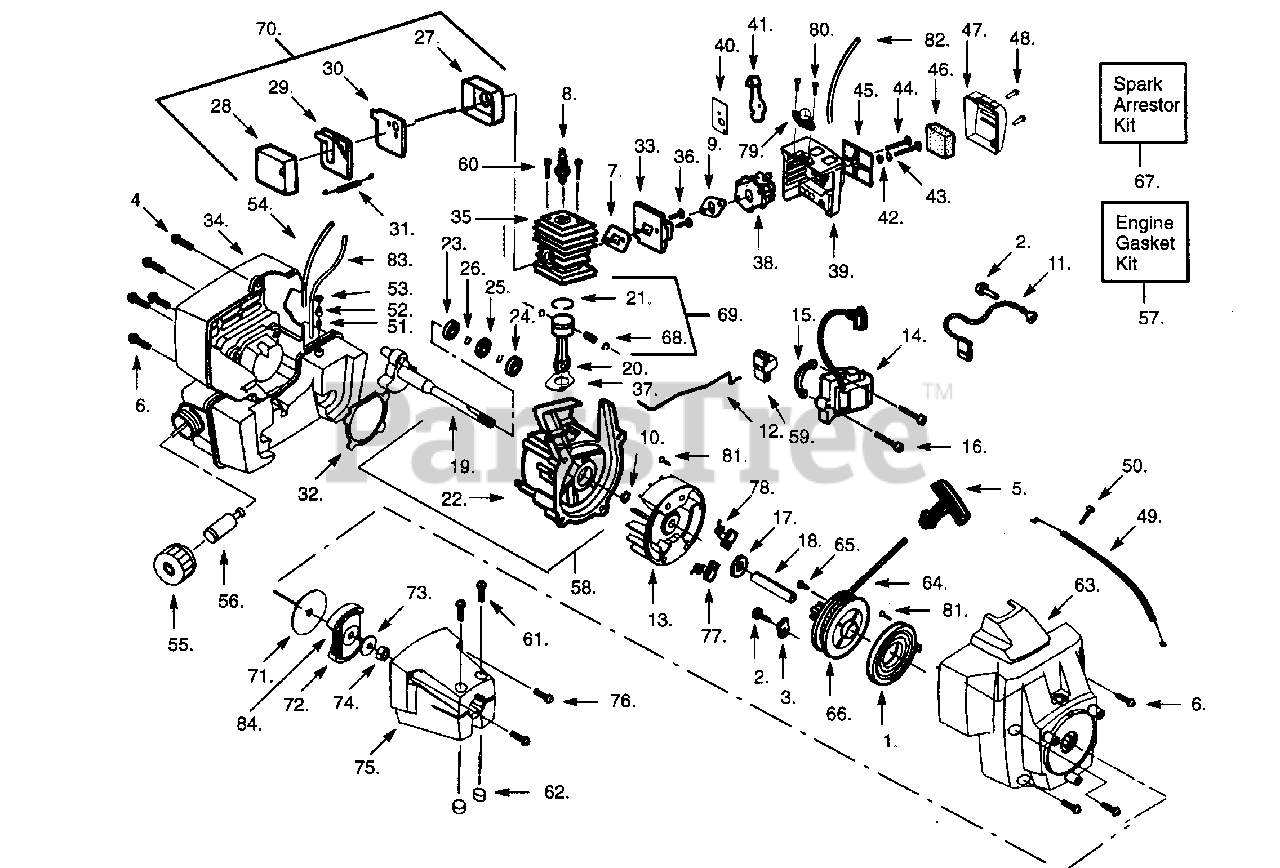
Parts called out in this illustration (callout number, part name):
1	Starter Spring
3	Retainer
5	Starter Handle
6	Screw
7	Cylinder Gasket
8	Spark Plug
10	Retainer
11	Lead Wire
12	Switch Wire Form
13	Flywheel Ass'y.
14	Ignition Module
19	Crankshaft Ass'y.
20	Connecting Rod Ass'y.
21	Piston Ring
22	Crankcase Ass'y.
23	Inner Bearing
24	Outer Bearing
25	C'case Seal
26	Retaining Ring
27	Muffler Body
28	Muffler Cover
29	Muffler Baffle-Exit
30	Muffler Baffle-First
31	Muffler Spring
34	Type 2 & 3
35	Cylinder
38	Type 1 (WT-245)
38	Type 2 (WT-299)
38	Type 2 (WT-380)
39	Type 2 & 3
40	Choke Plate
41	Choke Shutter
42	Wave Washer
43	Choke Spacer
45	Filter Plate
46	Air Filter Foam
47	Air Filter Cover
49	Throttle Cable Ass'y.
51	Check Valve
53	Retainer
54	Fuel Line-Prim./Carb
55	Fuel Cap Ass'y.
56	Fuel Pickup Ass'y.
57	Engine Gasket Kit (Inc. 7, 9, 32, 37)
58	C'case & C'shaft Assy. (Inc. 10,19,22-26)
59	Switch Button
63	Fan Housing
64	Rope Kit
66	Starter Pulley
67	Spark Arrestor Kit
68	Piston Pin Retainer
69	Piston Kit (Inc. 21,68 & Pin)
70	Muffler Kit
72	Clutch Ass'y.
75	Clutch Hsg.
77	Starter Dog
78	Starter Spring
79	Primer Bulb Ass'y.-Type 2 & 3
80	Screw-Type 2 & 3
81	Screw-Flywheel
82	Fuel Line-Prim./Tnk.
83	Fuel Line-Carb./Tnk.
84	Spring-Clutch
